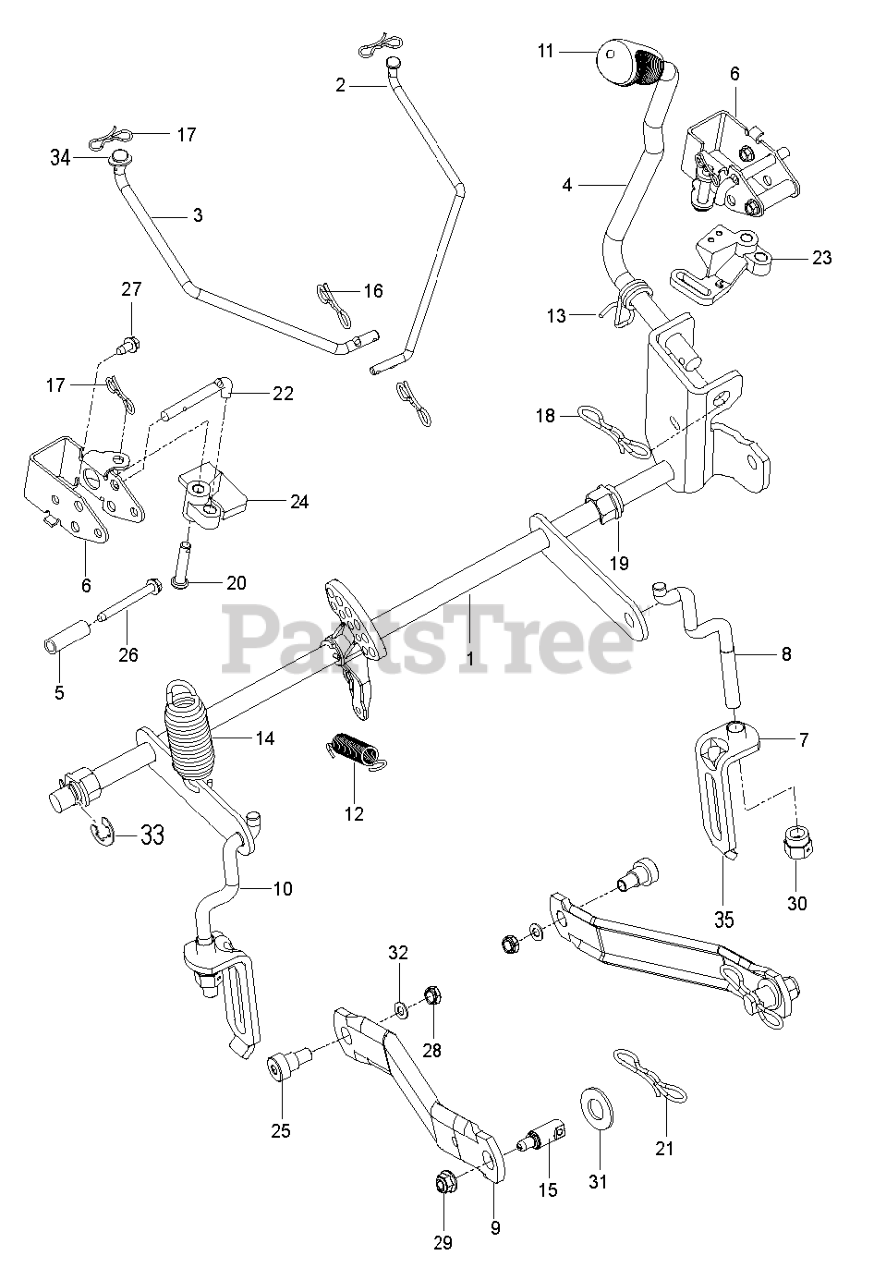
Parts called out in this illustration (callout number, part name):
1	SHAFT.ASM.RZ.DECK.LIFT.SRV
1	SHAFT ASSY DECK LIFT WELDMENT
2	LINK.BRAKE.PARK.UPPER.LH
3	LINK.BRAKE.PARK.UPPER.RH
4	LIFT.LEVER.ASM.RZ.SERVICE
5	SPACER.334.ID.5.OD.1.5.L
6	BRACKET.BELLCRANK.PBRAKE X431
7	ASSEMBLY, BRKT LINK
8	LINK, REAR SUSPENSION
9	ARM.RFIXED.MOWER.SUSPNSIONX431
10	LINK.ASM.RZ.LIFT.SERVICE
11	GRIP.HANDLE.LIFT.PVC.BLACK
11	GRIP.HANDLE.LIFT.PVC.428
12	RETURN.BRAKE.PARK.AUTO
13	SPRING.TORSION.LIFT.HANDLE
15	STUD.FASTNER.W/ANTI-ROTATE
16	PIN.COTTER.5/16.BOW TI
17	PIN COTTER;LOCKING;BOWTIE;1IN
18	PIN.COTTER.7/16.BOW TI.
19	PLASTIC NUT
20	PIN.5.16X1.5
21	PIN.COTTER.7/16.BOW TI.
22	ROD.PUSH.BRAKE
23	BELLCRANK.LH
24	BELLCRANK.RH
25	SB 3/8-16 X 3/8 SKT HD ZD
26	SCREW THD;ROLL;1/4-20 X 2.25
27	SCREW.1/4-20X5/8
28	NUT HEX 3/8-16 NYLON, THIN
29	5/16-18 NYLOC FLANGE NUT
30	BUSHING ALIGNMENT LINK LIFT
30	NUT, LIFT LINK 7/16-20
31	WASHER
32	WASHER
33	RETAINING RING LT
34	WASHER PLAIN WASHER 3/8 X 0.08
35	BRACKET CONNECT LINK LIFT
